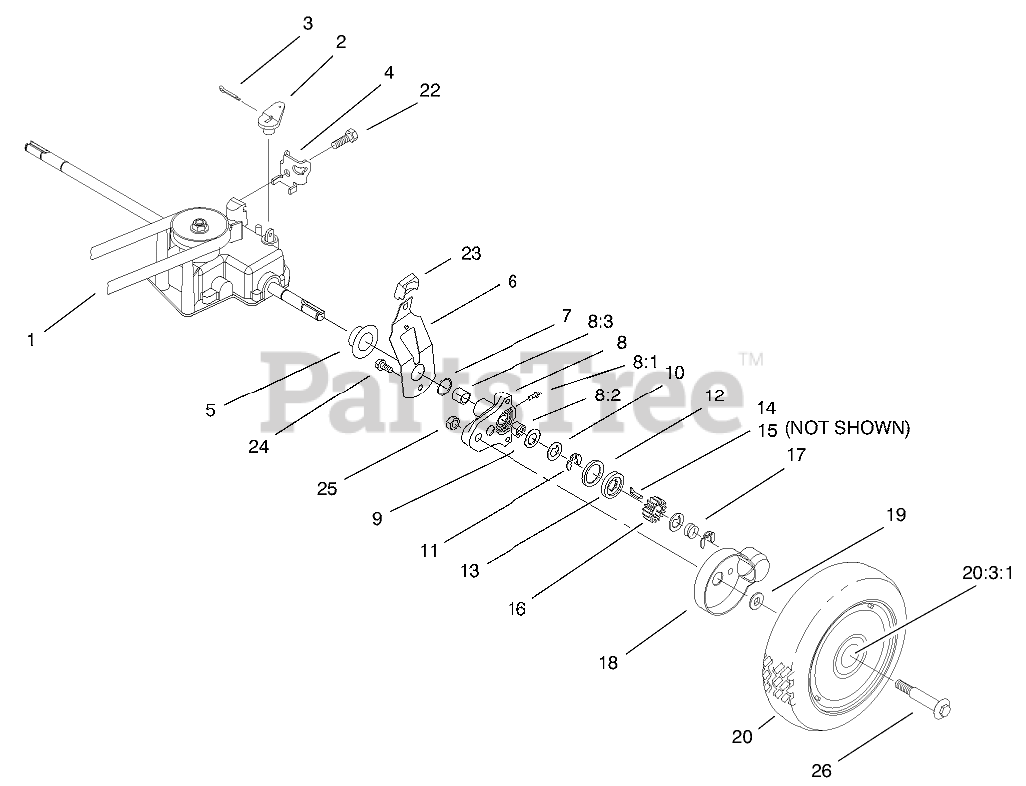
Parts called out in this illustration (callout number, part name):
1	V-BELT E
2	LEVER-SHIFT
3	PIN-COTTER
4	CLAMP-CABLE
5	CAP-END
6	SPRING ARM ASM
7	O-RING
8	PIVOT ARM ASM
8:1	FITTING-GREASE
8:2	BEARING-ROLLER
8:3	BUSHING
9	WASHER-ARM, PIVOT
10	WASHER-THRUST, KEYED
11	RING-CLIP, LOCKING
12	RING-FRICTION
13	WASHER-CLUTCH
14	KEY-ROCKING, LH
15	KEY-ROCKING, RH
16	GEAR-PINION
17	SPRING-COMPRESSION
18	COVER-WHEEL
19	SPACER-COVER, WHEEL
20	WHEEL AND TIRE ASM (W/GEAR)
20	WHEEL ASM
20:3	Wheel and Tire ASM
20:3:1	BUSHING
22	SCREW-HWHTF
23	KNOB-ARM
24	SCREW-HWH
25	NUT-LOCK
26	BOLT-WHEEL
26	Bolt-Wheel (Serial No. 9900001-9900102)
